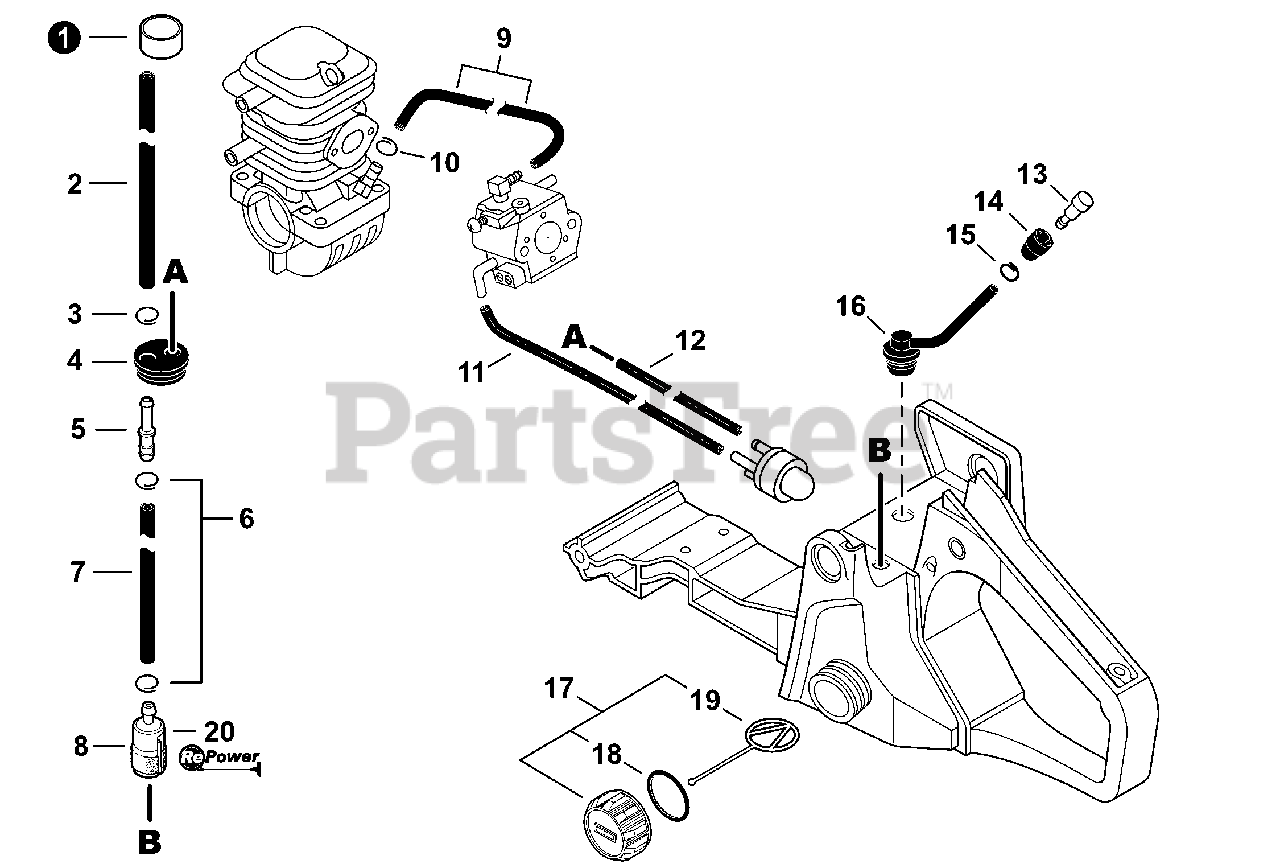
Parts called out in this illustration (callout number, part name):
1	TUBE 8×9×16
2	PIPE, FUEL - 3×5×182 - BLACK
4	GROMMET, FUEL
5	CONNECTOR, PIPE Ø5ר3.5
6	CLIP Ø6
7	PIPE, FUEL - 3×5×68 - BLACK
8	FILTER, FUEL
9	PIPE, PULSE 2.4×6×105
10	CLIP Ø6
11	PIPE 2.4×5×150 BLACK
12	PIPE 2.4×5×200 BLACK
13	VENT ASSY
14	HOLDER, VENT
15	CLIP Ø6.5MM
16	PIPE, VENT 3×6×65
17	CAP ASSY, FUEL
18	O-RING 22
19	CONNECTOR, CAP L= 60mm
20	TUNE-UP KIT - REPOWER
